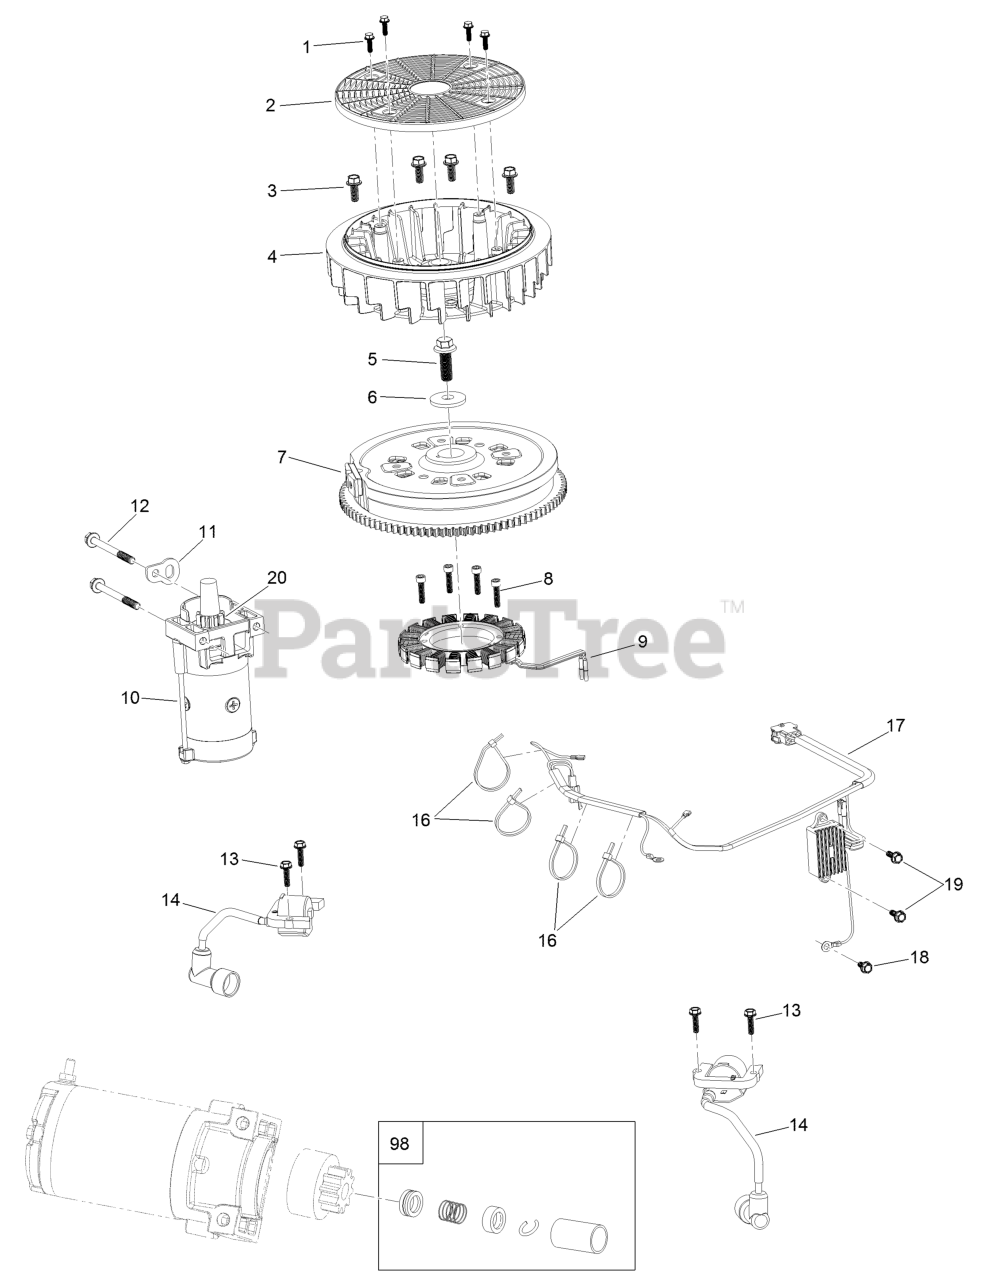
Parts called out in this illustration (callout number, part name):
1	Screw-HWH
2	Screen-Rotating
3	Screw-HWH
4	Fan-Cooling
5	Screw-HWH
6	Washer-Flat
7	Flywheel
8	Screw-HSH
9	Alternator
10	Motor-Starter
11	Bracket-Lift
12	Screw-HHF
13	Bolt-Flange
14	Ignition Coil ASM
16	Tie-Zip
17	Regulator-Voltage W/Harness
18	Screw-HHF
19	Screw-HHF
20	Pinion-Starter
98	Starter Repair Kit
